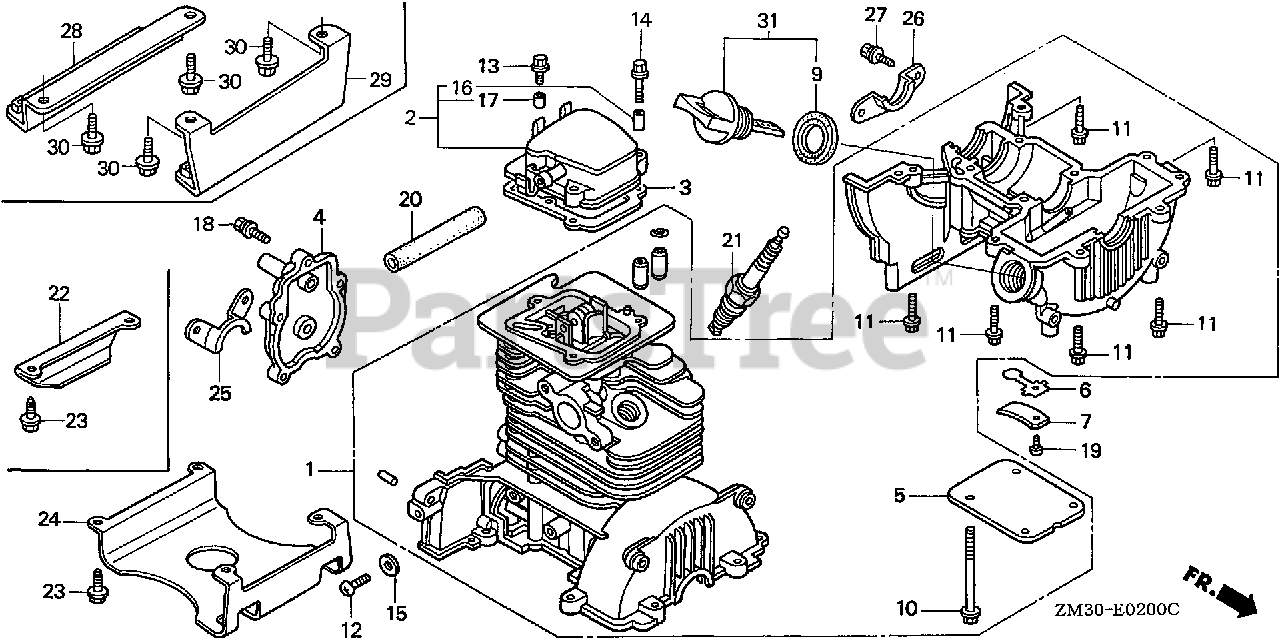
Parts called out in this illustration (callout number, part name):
1	CRANKCASE SET
2	COVER, HEAD
3	GASKET, HEAD COVER
4	COVER, CAMSHAFT
5	COVER, OIL OUTLET VALVE
6	VALVE, OIL OUTLET
7	PLATE, STOPPER
9	GASKET, OIL FILLER CAP
10	BOLT, FLANGE (5X55)
11	BOLT, FLANGE (5X18)
12	SCREW, PAN (6X8)
13	BOLT, FLANGE (5X14)
13	BOLT, FLANGE (5X12)
14	BOLT, FLANGE (5X22)
15	WASHER, SEALING (6.5MM)
16	COLLAR, HEAD COVER
17	COLLAR, TOP COVER
17	COLLAR A, HEAD COVER
18	BOLT-WASHER (4X16)
19	SCREW, PAN (3X5)
20	BULK HOSE, VACUUM (7X3000) (7X68)
21	SPARK PLUG (CR5HSB)
22	STAND
23	BOLT, FLANGE (5X12)
24	GUARD, TANK
25	GUARD A, GRASS
26	GUARD B, GRASS
27	BOLT-WASHER (4X10)
31	CAP ASSY., OIL FILLER
